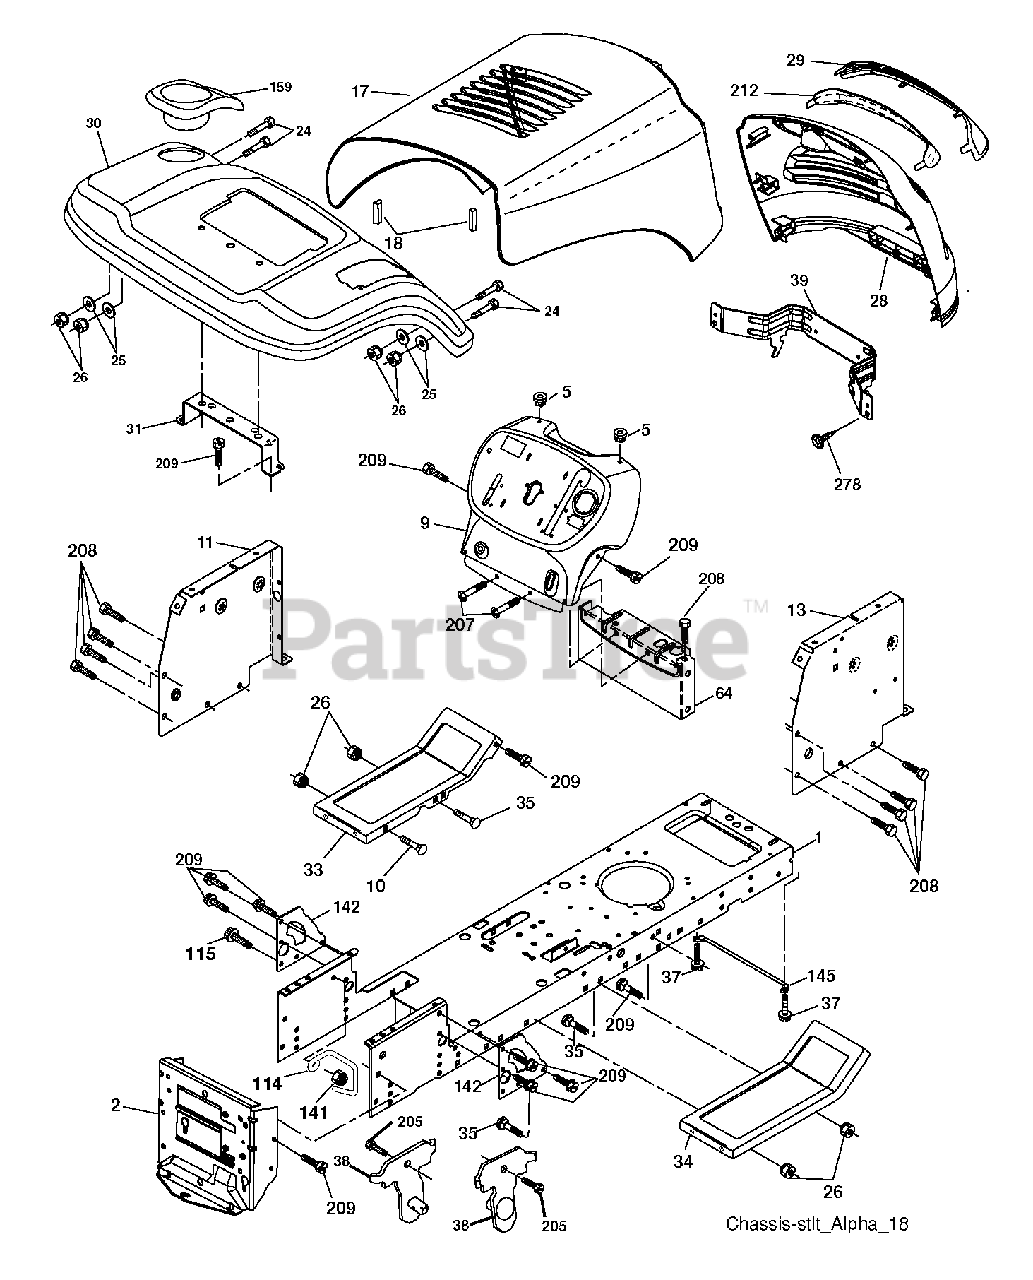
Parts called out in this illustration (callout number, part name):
1	CHASSIS STAMPING
2	DRAWBAR, 12GA
5	BUMPER.RUBBER.HOOD
11	PANEL.DASH.LH.LTX
17	HOOD.STEEL.ELITE.YELLOW
18	BUMPER.HOOD.LARGE.1.75"
25	WASHER
26	NUT
28	GRILLE.ELITE.BASIC.LT.BLACK
29	LENS.GRILLE.BASIC.BAR.LT.CLR
30	FENDER.LTST.W/SHFT.CUP.YELLOW
31	BRACKET FENDER
33	FOOTREST.LH.YELLOW
34	FOOTREST.RH.YELLOW
37	SCREW LT
38	BRACKET.ASM.PIVOT.MOWER.REAR
39	BRACKET PIVOT
64	DASH LOWER
115	SCREW.3/8-16
141	NUT LOCK FLG 3/8-16 UNC
142	PLATE REINFORCEMENT
145	ROD.PIVOT.HOOD
159	CUPHOLDER.BLACK
205	SCREW LT
207	SCREW, 5/16-18 X 1/2
208	SCREW 3/8-16X1/2
209	SCREW, 3/8-16X3/4
212	INSERT.LENS.REFLECTIVE.LEFT
278	SCREW.#10 X 0.750.BOS (2 2)
